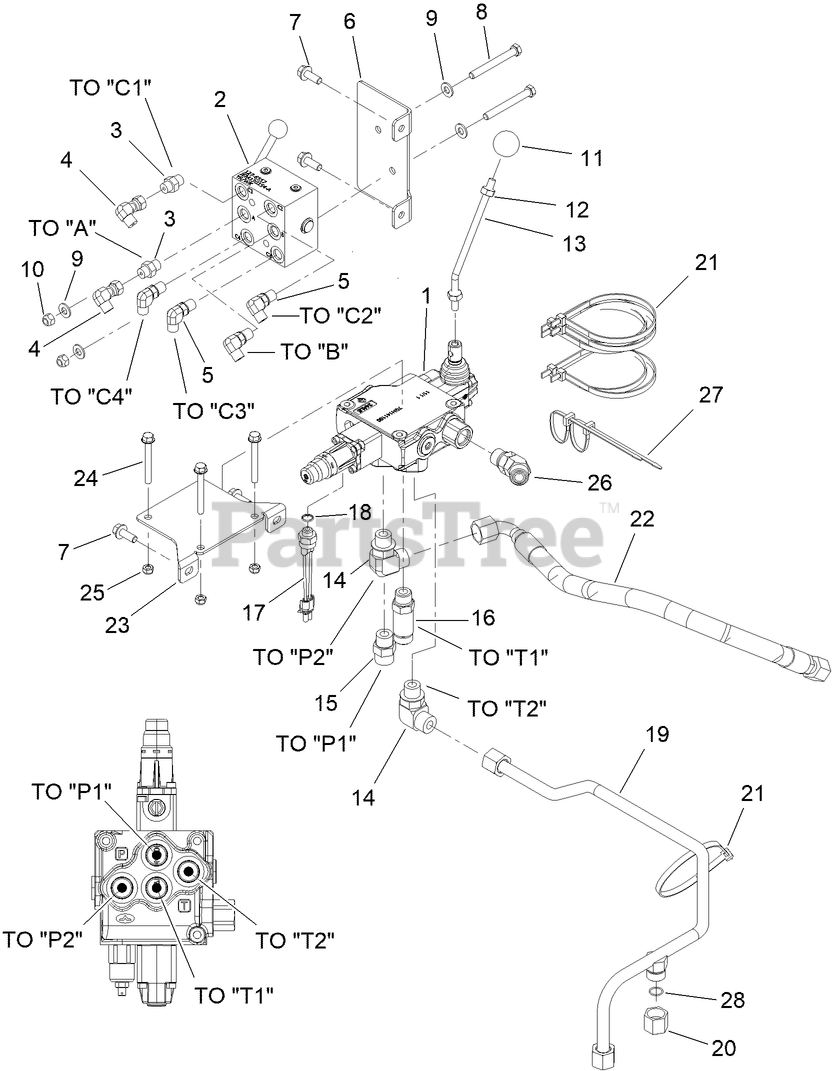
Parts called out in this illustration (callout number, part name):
1	VALVE-TRENCHER
2	CONTROL SELECTOR VALVE ASM
3	CONNECTOR (04O-06S)
4	UNION (04O-04OFX90)
5	FITTING-ELBOW, 90 DEG
6	SELECTOR VALVE BRACKET
7	SCREW-HHF
8	SCREW-HH
9	WASHER-FLAT
10	NUT-HEX
11	KNOB-ROUND
12	NUT
13	LEVER-TRENCHER
14	CONNECTOR (10S-10O90)
15	CONNECTOR (10S-10O)
16	CONNECTOR (10O-10S, LG)
17	SWITCH-BALL
18	O-RING (906 D90)
19	HARDLINE (-10 TRENCHER TO RETURN)
21	TIE-CABLE
22	HOSE (10OFX90S-26.5"-3000)
23	BRACKET-TRENCHER VALVE
24	SCREW-HHF
25	NUT-LOCK, NI
26	CONNECTOR (10S-10O45)
27	TIE-CABLE
28	O-RING (016 D90)
